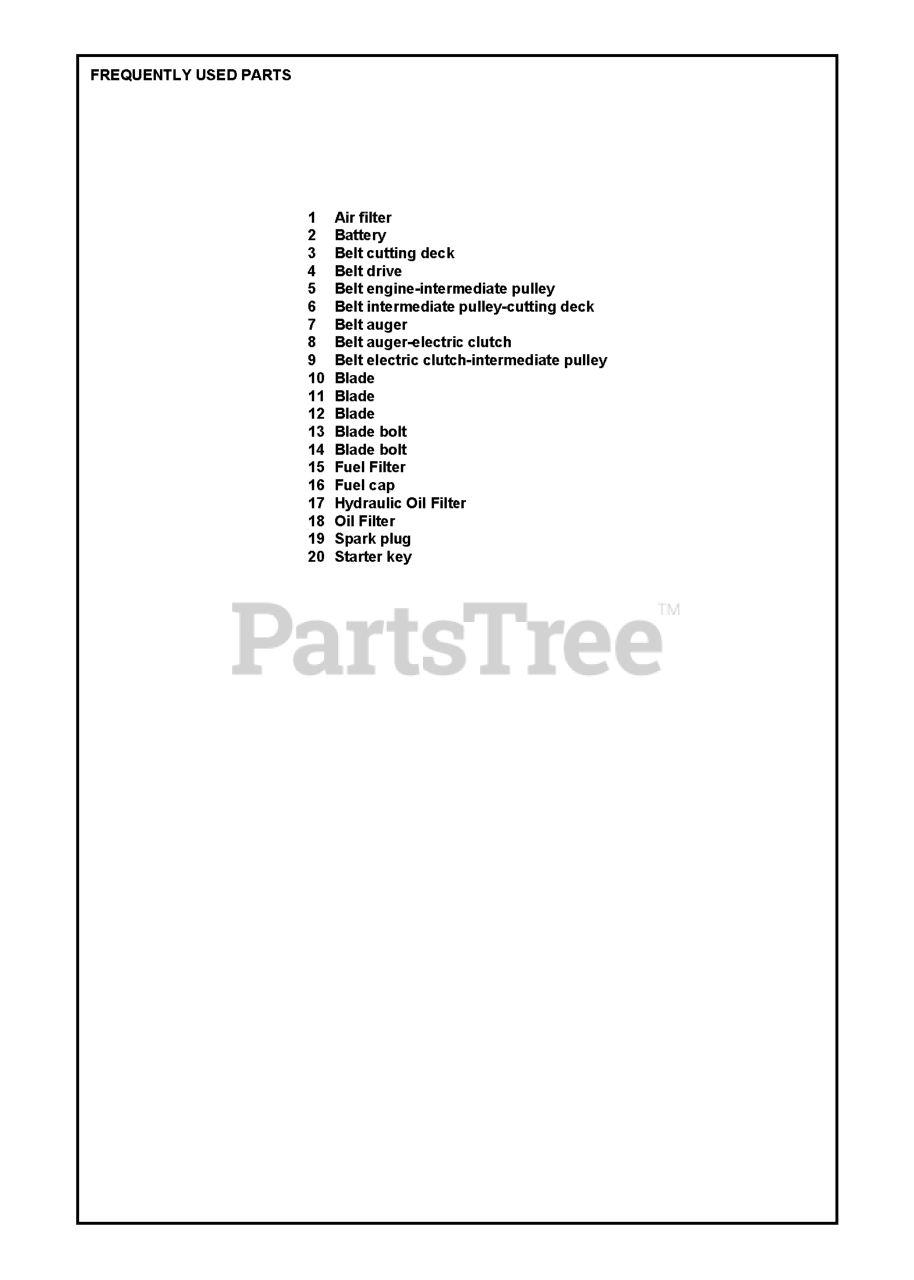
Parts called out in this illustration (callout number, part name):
1	GUARD.ENGINE.HUSQ.RZ.X498
2	FRAME, RT, ORANGE
3	FRAME, LT, ORANGE
4	TUBE.PNT.FRAME.RER.HUSQ.23".RZ
5	PLATE, FOOT W/DECALS RZ
6	FRONT COVER RZ REFRESH
7	FOOTREST.PLATE.SUPPORT.X431
8	SCREW.ADJ.ISOLATOR.BOLT.ASSY
9	LIGHT.ZTR.LED.ASM
10	GROMMET.RUBBER.PUSHIN
11	GROMMET.BUMPER
12	CROSS.PNT.MEMBER.BLK
13	BRACKET.SKIDPLTE.LED.RFRSHX417
14	COVER.RAIL.RH.RZ.X668
15	COVER.RAIL.LH.RZ.X668
16	CAP.ASSY.FUEL.3".N-EPA.GRY.498
16	KNOB W/STUD
17	BUSHING SPHERICAL SUSP. FRONT
18	LINK, FRONT SUSP.
19	FENDER.SUPPORT.PNT.X431
20	IGNITION KEY
20	SUPPORT.PNT.RH.CONSOLE.FRONT
21	SUPPORT.PNT.LH.CONSOLE.FRONT
22	BRKT ROD.BYPASS.EZT.X431
23	BOLT.FIN HEX 5/16-18UNC X2 1/4
25	BOLT.HEX.FIN.3/8-16 X 3.GR5
26	BOLT.CARRIAGE.5/16-18.7/16
27	HHFS 3/8-16 X 3 GRD 5 ZD
28	BOLT SHOULDER,FLANGED,3/8-16X3
29	BOLT.5/16-18.THRD.ROLL.SHOULDR
30	BOLT.5/16-18.THRD.ROLL.SHOULDR
31	SCREW.#10 X 0.750.BOS
32	SCREW.#10 X 0.500
33	NUT LOCK HEX FLANGE 5/16-18
34	5/16-18 NYLOC FLANGE NUT
35	NUT 3/8-16 HEX FLG NYLOC ZD
36	7/16-14 HEX NUT W/NYL RING ZD
37	NUT ACORN,FLANGED,5/16-18
38	WASHER
39	WASHER 5/16"
